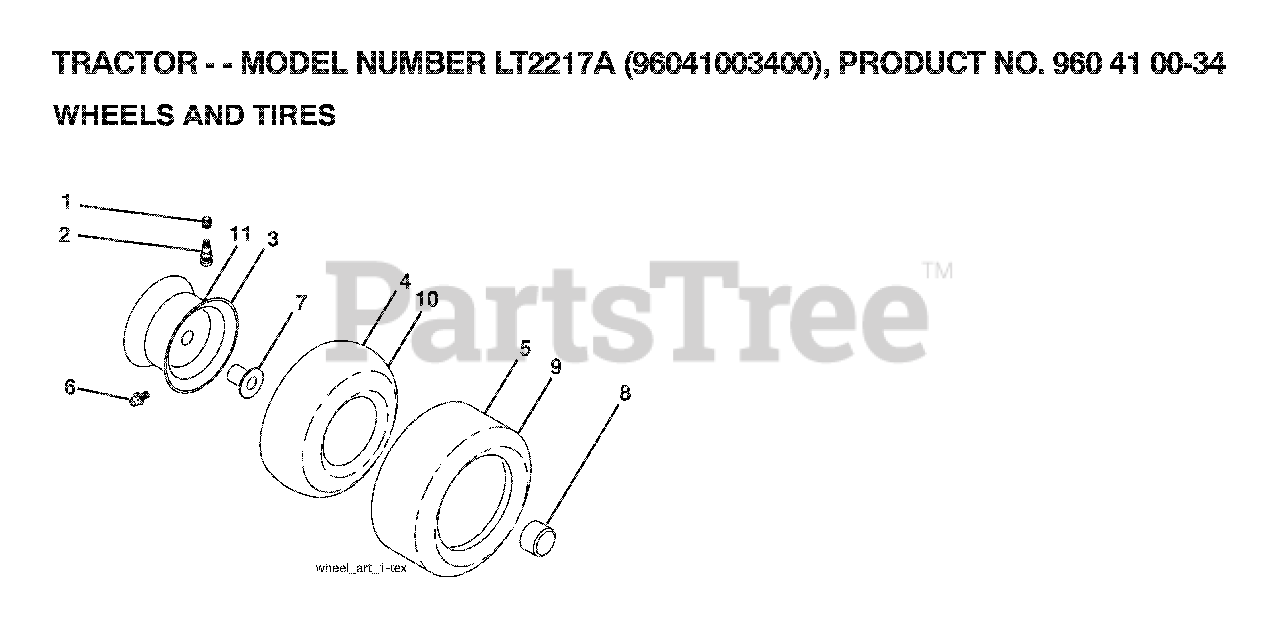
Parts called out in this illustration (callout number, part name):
1	VALVE CAP
2	VALVE STEM LT
3	RIM ASM 6" FRONT SILVER
4	TUBE.5.3/4.5/6
5	TIRE HEAVY DUTY
6	FITTING LT
7	BEARING T
8	CAP, AXLE BLK
9	TIRE HEAVY DUTY
10	TUBE
11	RIM ASM 8" REAR SILVER
